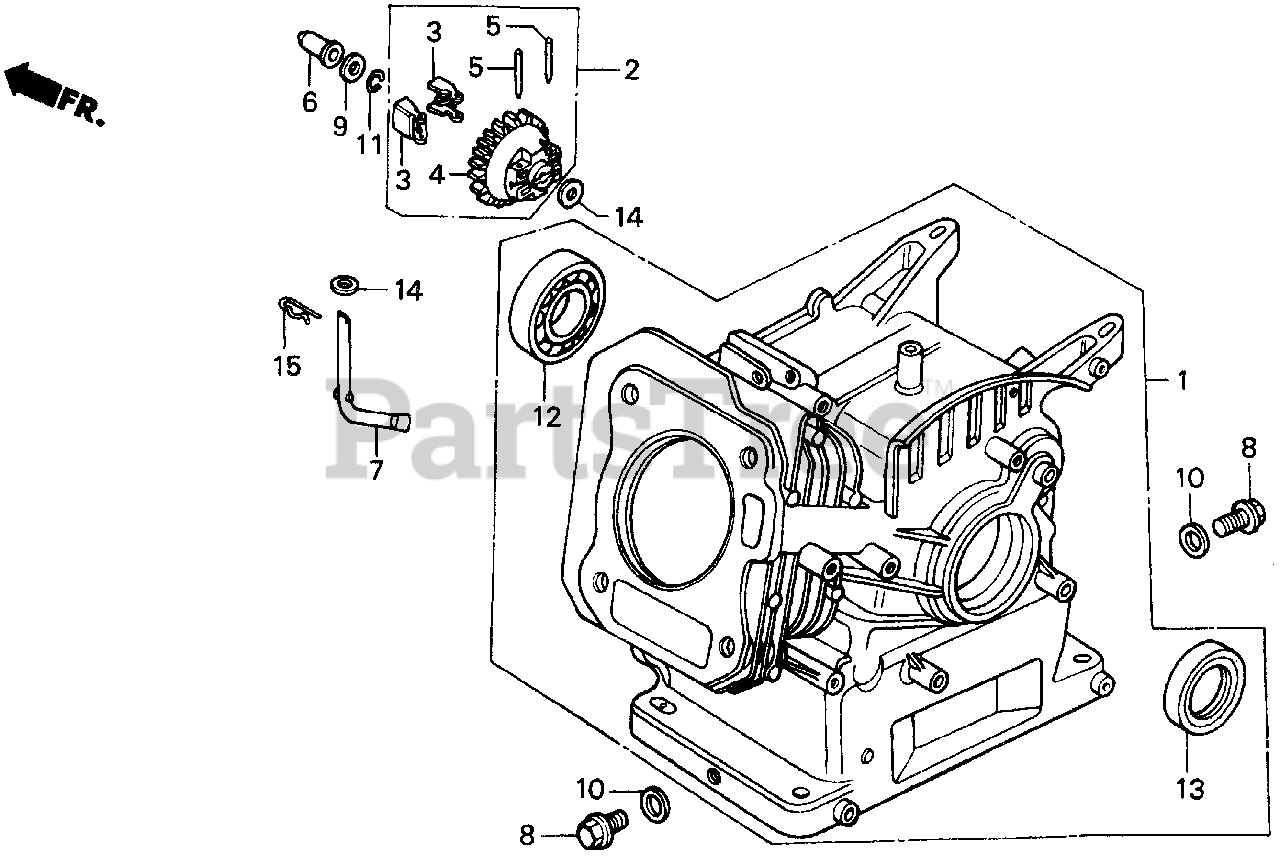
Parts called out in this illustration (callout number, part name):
1	CYLINDER ASSY.
2	GOVERNOR ASSY.
3	WEIGHT, GOVERNOR
4	HOLDER, GOVERNOR WEIGHT
5	PIN, GOVERNOR WEIGHT
6	SLIDER, GOVERNOR
7	SHAFT, GOVERNOR ARM
8	BOLT, DRAIN PLUG
9	WASHER, THRUST (6MM)
10	WASHER, DRAIN PLUG (10.2MM)
11	CLIP, GOVERNOR HOLDER
12	BEARING, RADIAL BALL (6205TMB) (NTN)
13	OIL SEAL (25X41X6)
14	WASHER, PLAIN (6MM)
15	PIN, LOCK (8MM)
